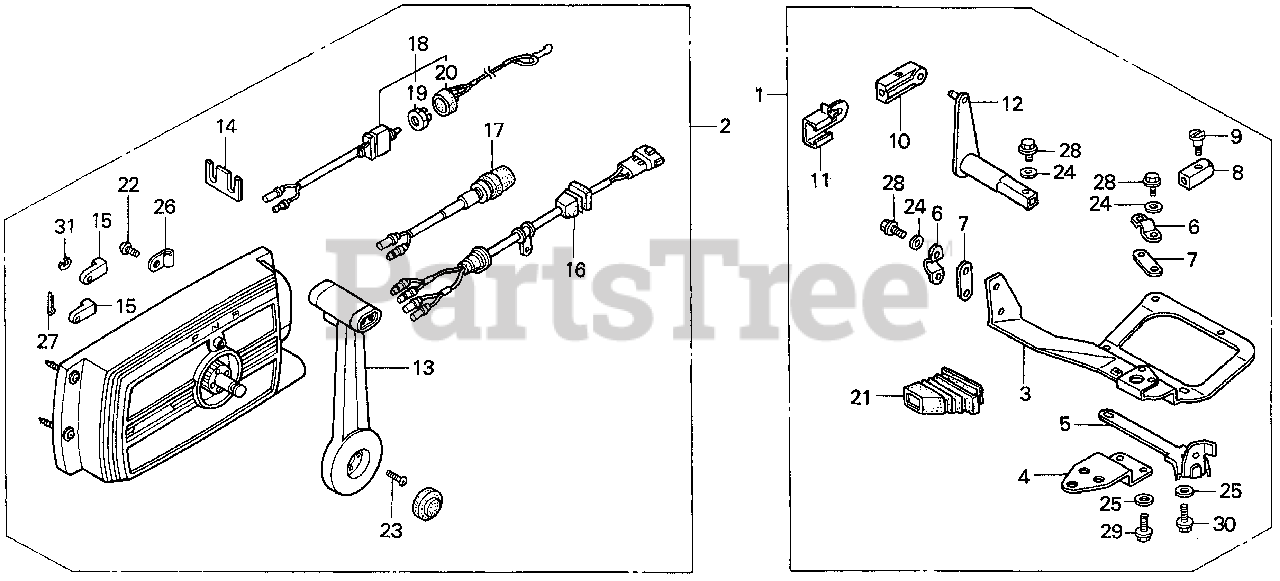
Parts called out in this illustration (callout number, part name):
1	CONTROL KIT, REMOTE
2	CONTROL BOX KIT, OUTBOARD MOTOR
3	BRACKET, STEERING
4	PLATE, STEERING
5	PLATE, STEERING STOPPER
6	CLAMP, CABLE
7	SHIM, CABLE CLAMP
8	NUT, CONTROL ADJUSTING
9	BOLT, CONTROL ADJUSTING
10	PIVOT, SHIFT
11	PLATE, LOCK
12	PEDAL, GEARSHIFT
13	LEVER, CONTROL BOX
14	PLATE, CABLE CLAMP
15	PIVOT, SHIFT
16	CABLE ASSY., REMOTE CONTROL
17	SWITCH ASSY., ENGINE STOP
18	SWITCH KIT, SAFETY
21	RUBBER, SEALING
24	WASHER, PLAIN (5MM)
25	WASHER, PLAIN (6MM)
26	CLAMP, CORD
27	PIN, SPLIT (2.0)
28	BOLT, HEX. (5X12)
29	BOLT, HEX. (6X16)
30	BOLT, HEX. (6X18)
31	E-RING (5MM)
